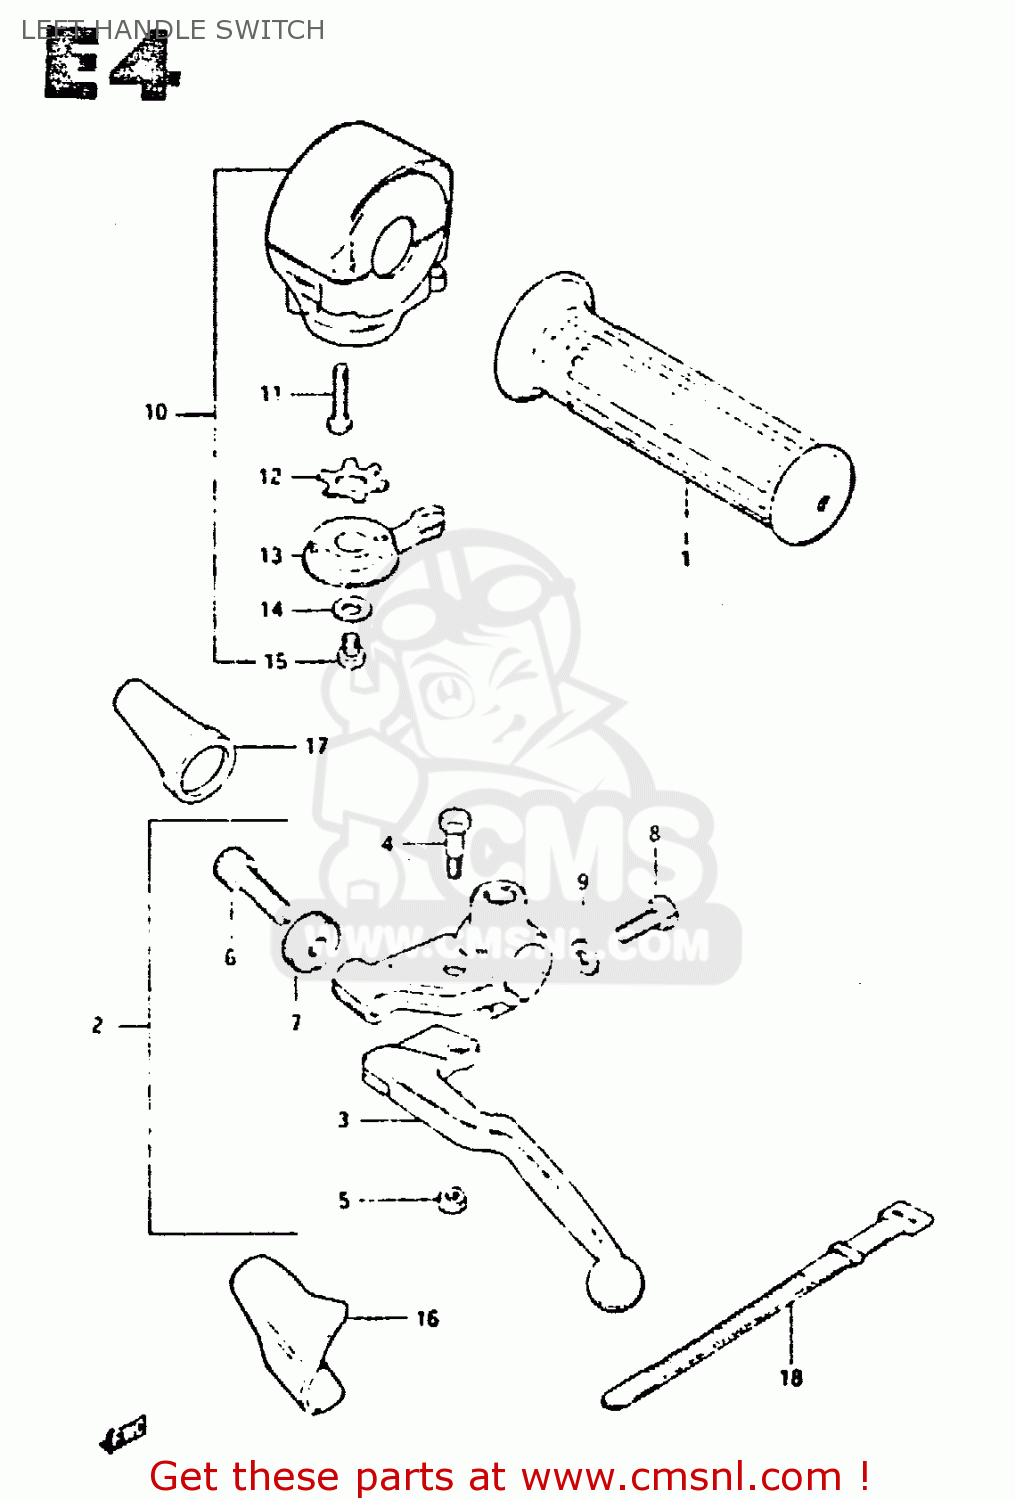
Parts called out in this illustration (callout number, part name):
1	GRIP,LEFT
2	LEVER ASSY, CLUTCH
3	LEVER,CLUTCH
4	BOLT,LEVER PIVOT
5	NUT
6	ADJUSTER,CABLE
7	NUT,CABLE ADJUSTER
8	BOLT
9	WASHER
10	SWITCH ASSY,HA
11	SCREW
12	WASHER
13	LEVER,STARTER
14	WASHER 6MM
15	SCREW
16	COVER,CLUTCH LEVER
17	BOOT,CLUTCH CABLE
18	CLAMP(L:120)
